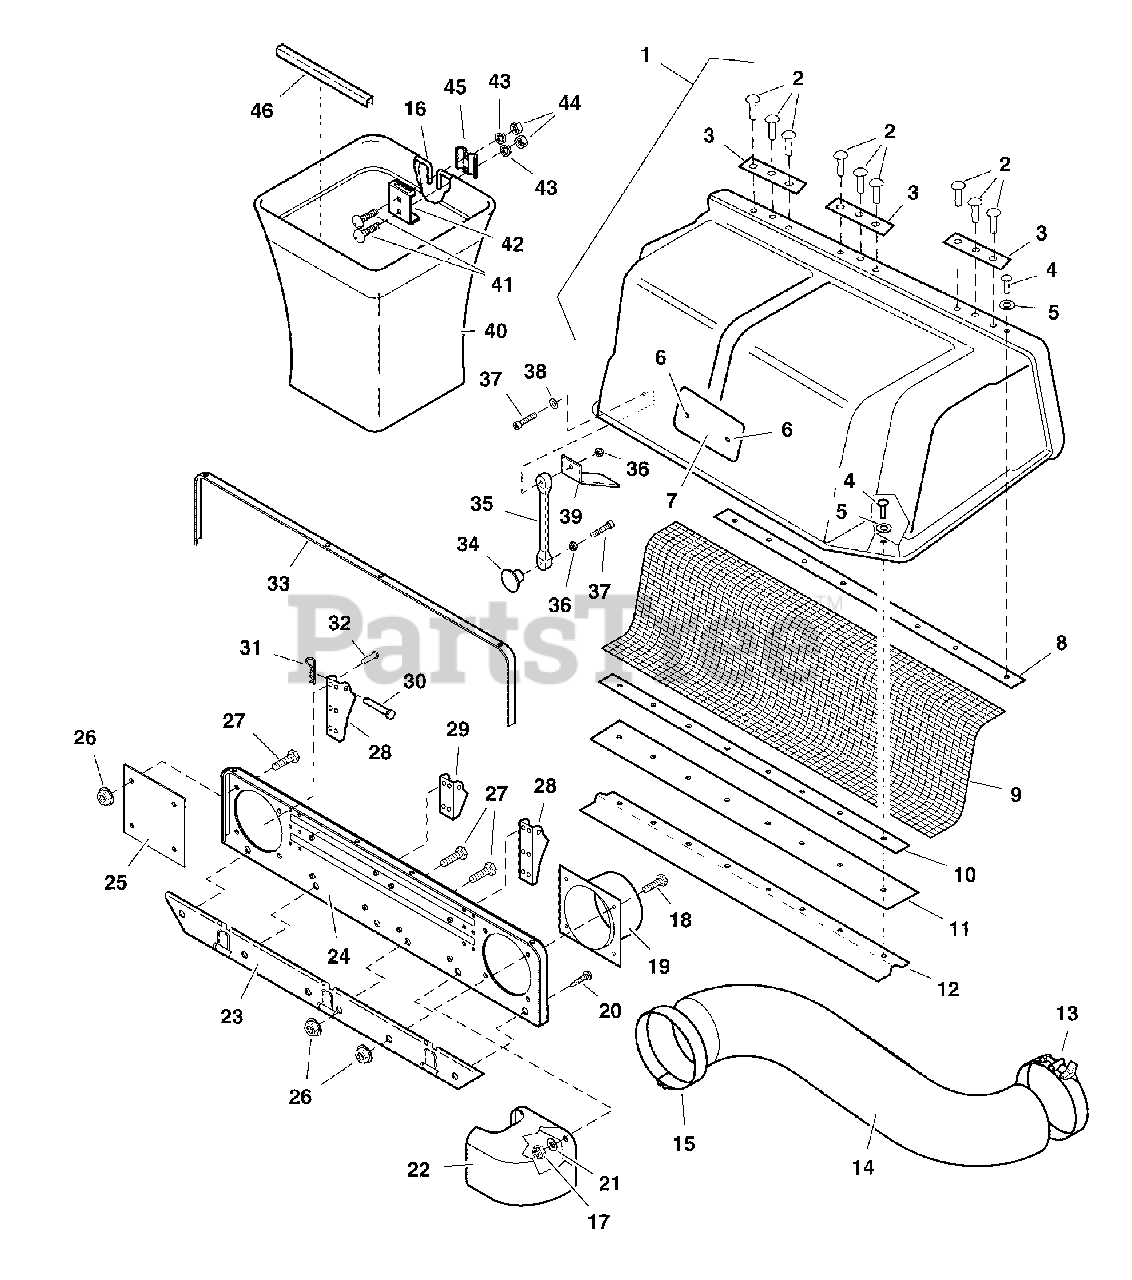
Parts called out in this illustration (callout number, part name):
1	COVER & SCREEN ASSEMBLY
2	BOLT, 1/4-20 x 3/4
2	BOLT,1/4-20X5/8
3	HINGE ASSEMBLY
6	CLIP, Canoe
7	DECAL, Safety
10	CLAMP, Seal
12	ANGLE, Screen
13	HOSE CLAMP, Lower
14	HOSE
15	HOSE CLAMP, Upper
17	NUT, 5/16-18 Hex Nylon Lock
18	BOLT, 5/16-18 x 1
19	HOSE ADAPTER
20	CAPSCREW, Taptite, 1/4-20 x 1/2
21	WASHER, 5/16" SAE
23	CHANNEL ASSEMBLY
24	PLATE ASSEMBLY
25	INLET COVER
26	NUT, 5/16-18 Hex Small Serrated Flange
27	BOLT, 5/16-18 x 3/4
30	PIN, 3/8 x 2-3/4
31	PIN, Hair
35	RUBBER STRAP
36	NUT, #10-32 Hex Nylon Lock
37	SCREW, #10-32 x 1-1/2
38	WASHER, 3/16" USS
39	COVER SUPPORT
40	BAG, Grass (Black)
41	CARRIAGE BOLT, 5/16-18 x 3/4
43	WASHER, 5/16" Lock
44	NUT, 5/16-18 Hex
46	TUBE CLIP, Grass Bag
